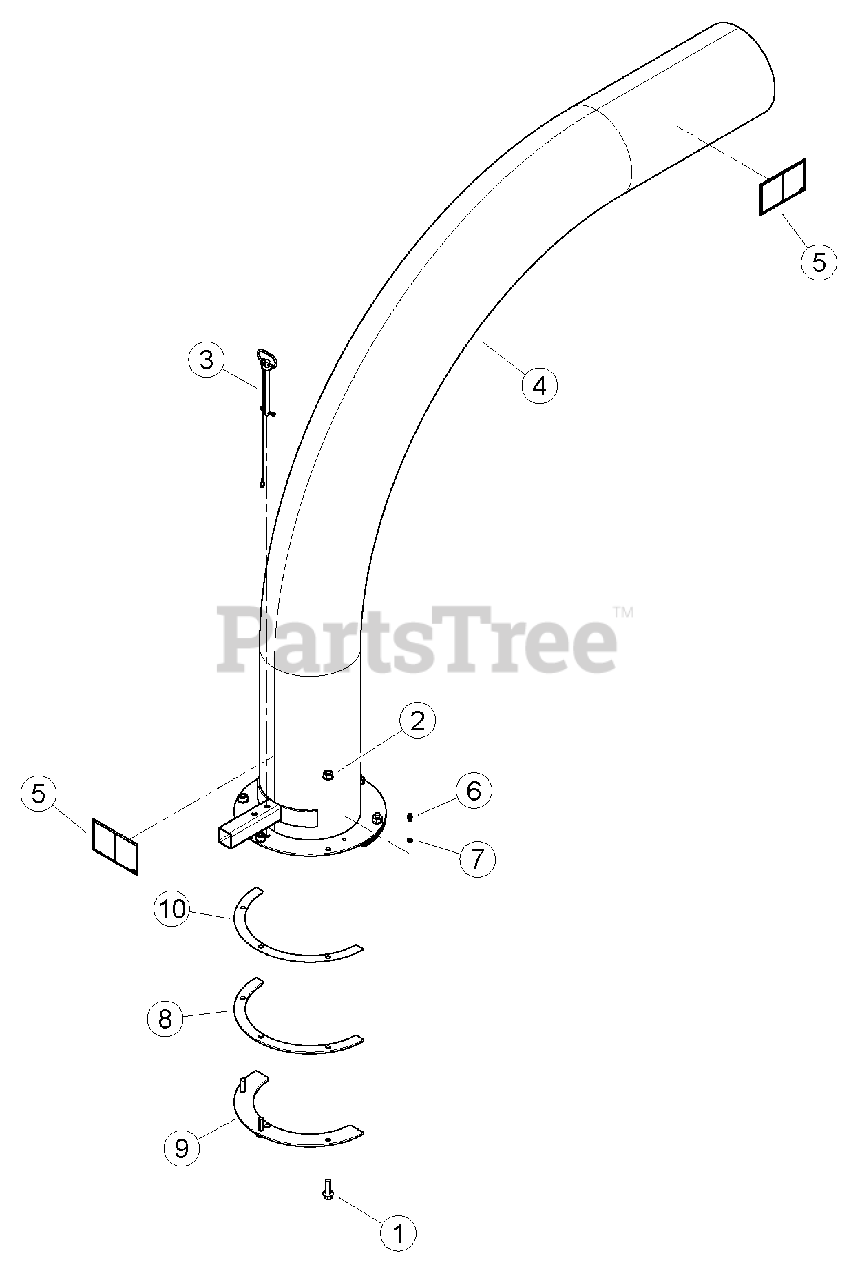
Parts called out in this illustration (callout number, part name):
1	BOLT, 3/8 X 1-1/4 FLANGE NC
2	NUT, 3/8-16 NYLOCK FLANGE
3	PIN, 3/8" X 4.25" DISCHARGE
4	ASSEMBLY, 12" DL DISCHARGE
5	DECAL, DISCHARGE ISO
6	FITTING, 1/4 SELF-TAP GREASE
7	WASHER, FLAT .254 X .400 X .048
8	RING, DISCHARGE SPACER
9	RING, DISCHARGE CLAMP
10	SHIM, DISCHARGE SPACER RING
